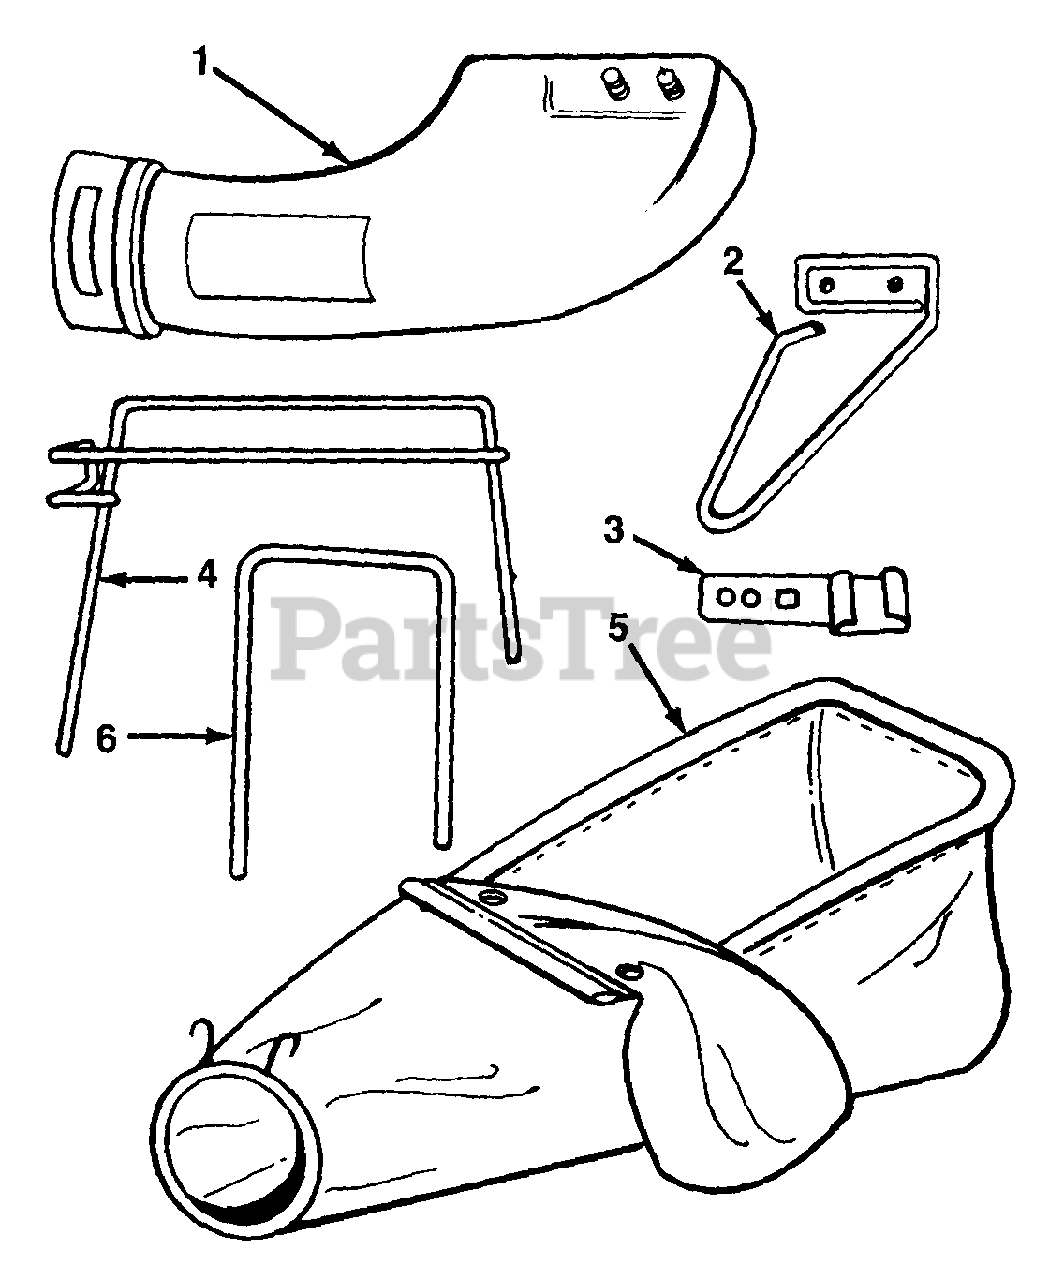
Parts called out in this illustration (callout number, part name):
1	Plastic Chute
2	Chute Mounting Bracket w/Wire
3	Handle Bracket
5	Bag w/Clamp Ring
6	Upper Support Tube
